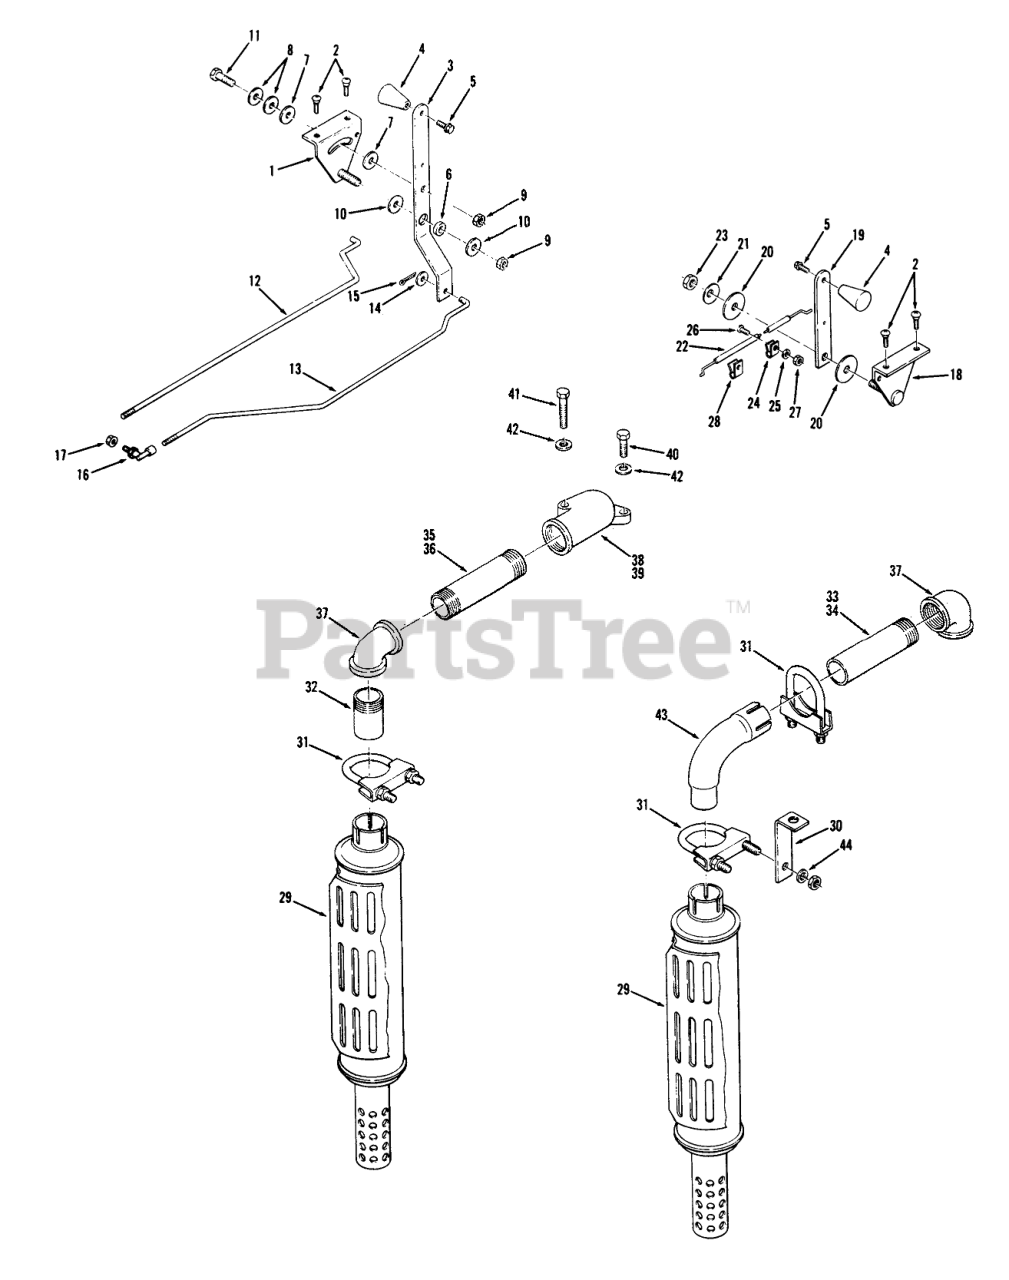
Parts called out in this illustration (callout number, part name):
1	Assy-Bracket
2	Screw, Special
3	Handle Throttle
5	Screw
6	SPACER CLUTCH ARM
7	FRICTION WASHER
8	WASHER-SPRING DISC
9	NUT
10	Washer-3/8
11	Bolt
12	Rod-Throttle
13	Rod-Throttle
15	Cotter Pin 3/32 X 1/2
16	BALL JOINT ASSY R
18	Assy-Bracket
19	HANDLE
20	FRICTION WASHER
21	WASHER-SPRING DISC
22	CABLE-CHOKE CONTROL
22	CABLE CHOKE CONTROL
23	NUT
24	CLIP BOWDEN WIRE
26	Screw
27	HEX NUT 10-32 E.S.
28	THROTTLE CONTROL CLP
29	ASSY-MUFFLER
30	Bracket
31	ASSY-MUFFLER CLAMP
32	Nipple
33	NIPPLE-EXHAUST 1X4
34	Nipple-1" x 6"
35	Nipple 5 in. Long
36	Nipple 2 1/2 in. Long
37	ELBOW
38	Fitting Exhaust RH
39	Fitting Exhaust LH
40	Bolt
41	HHCS
42	Lockwasher
43	TUBE-INLET
44	WASHER 5/16 SAE
